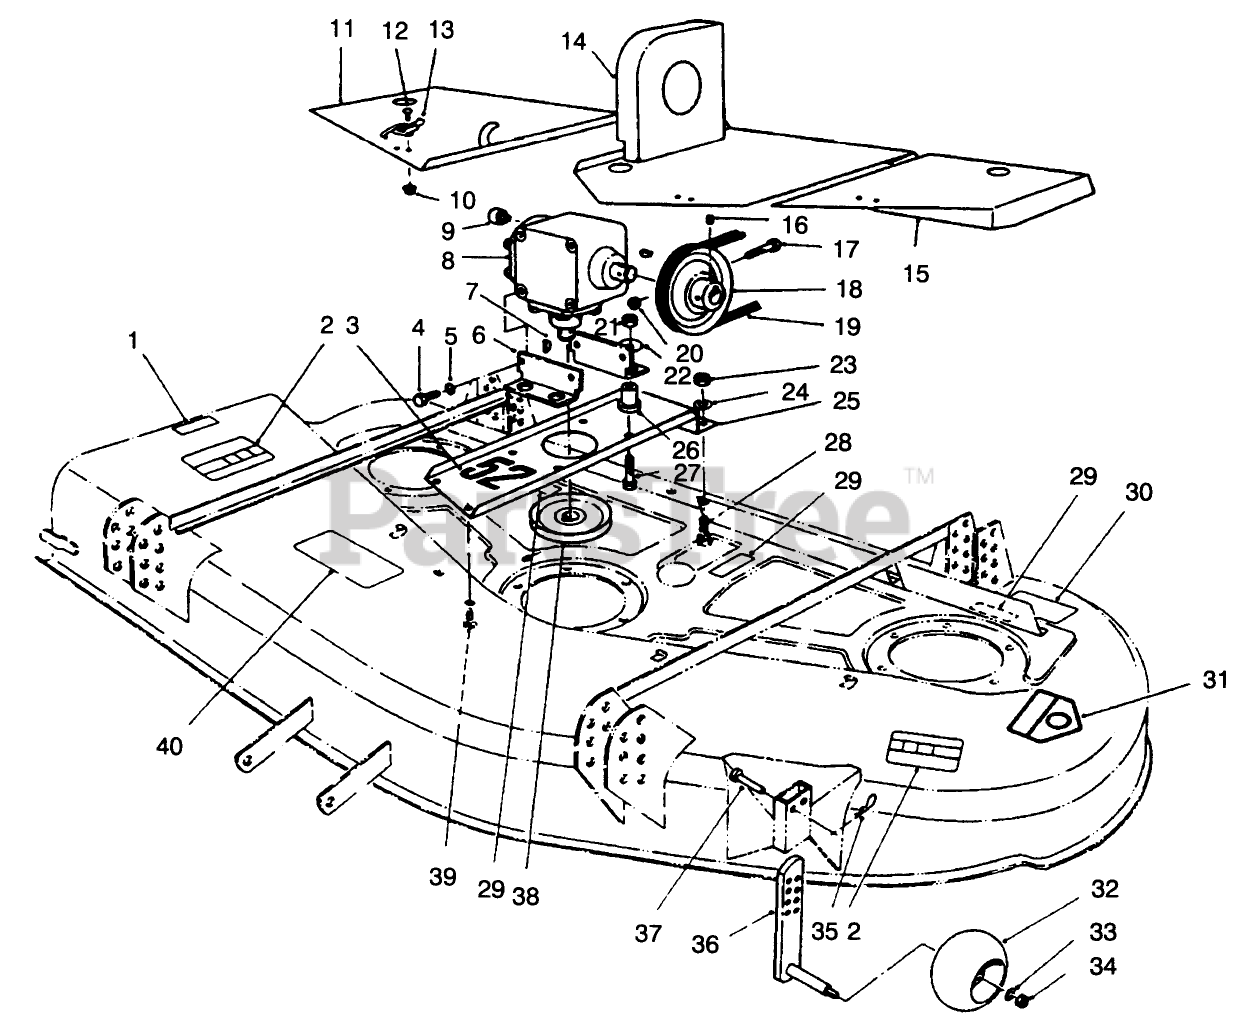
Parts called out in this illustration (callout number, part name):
1	DECAL-DANGER
2	DECAL-DANGER, THROWN OBJECT
3	DECAL
4	SCREW-HH
5	WASHER-LOCK
6	Bracket Mounting
8	Gear Box
9	FITTING-LUBE
10	NUT-LOCK, FLANGE
11	Bolt
12	SCREW-HWH
13	CLAMP-SLOTTED
14	Center-Cover
15	Cover-Deck
16	SCREW-SET, SQH
17	SCREW-HH
18	PULLEY
19	V-BELT, DECK
20	NUT-LOCK, NI
21	NUT-LOCK, SIDE
22	WASHER
23	NUT-LOCK, NI
24	WASHER-FLAT
25	Base-Gear Box Mount
26	MOUNT
27	SCREW-HH
28	SCREW-HH
29	DECAL-DANGER
30	DECAL-TORQUE
31	DECAL-DANGER
32	WHEEL-GAGE
33	WASHER-FLAT
34	NUT-LOCK, NI
35	PIN-HAIR
36	GAGE-WHEEL
37	PIN-CLEVIS
38	Pulley
39	BOLT-CARR
40	DECAL-WARNING
